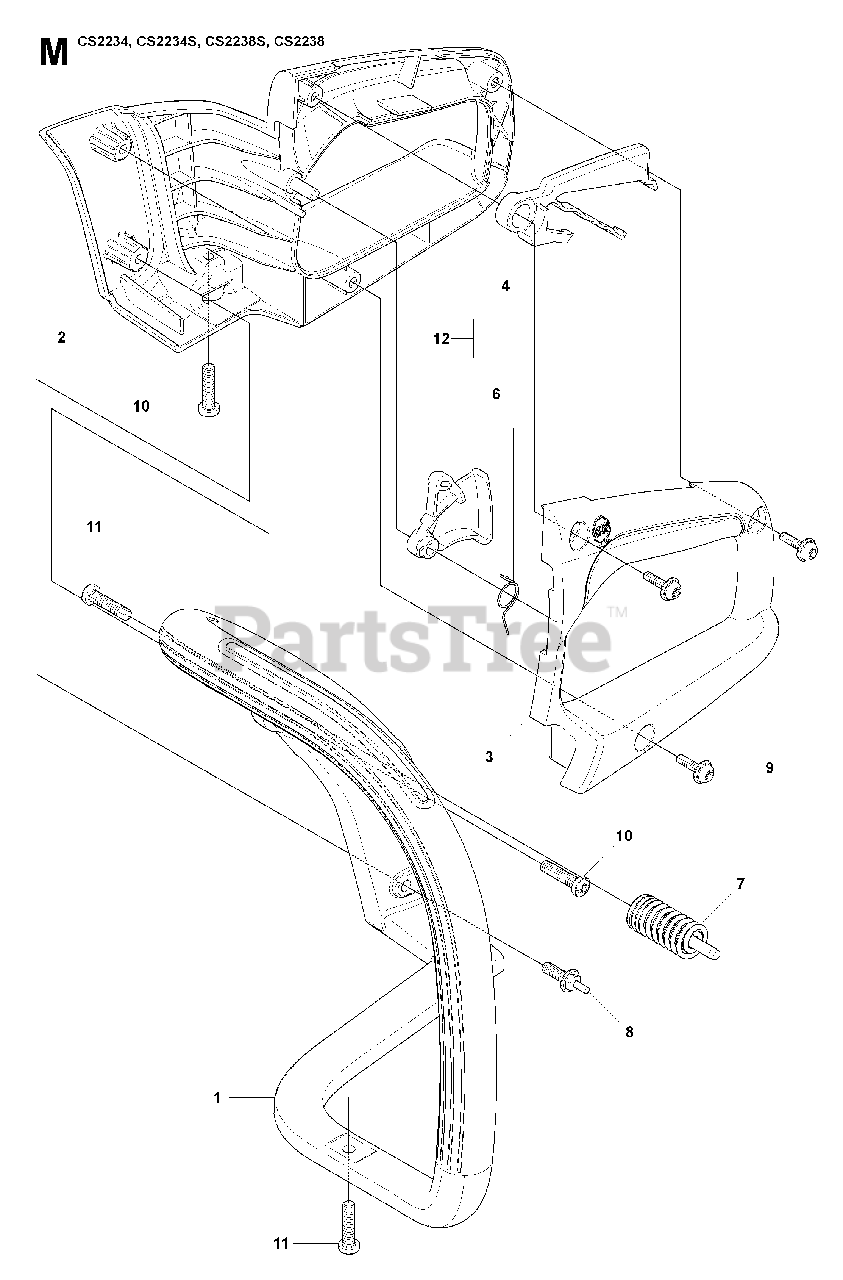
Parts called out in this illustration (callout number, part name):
1	HANDLE FRONT
2	HANDLE REAR
10	SCREW FILTER PLATE
11	SCREW M5.38-14X22.225MM
12	KIT TRIGGER LOCKOUT
